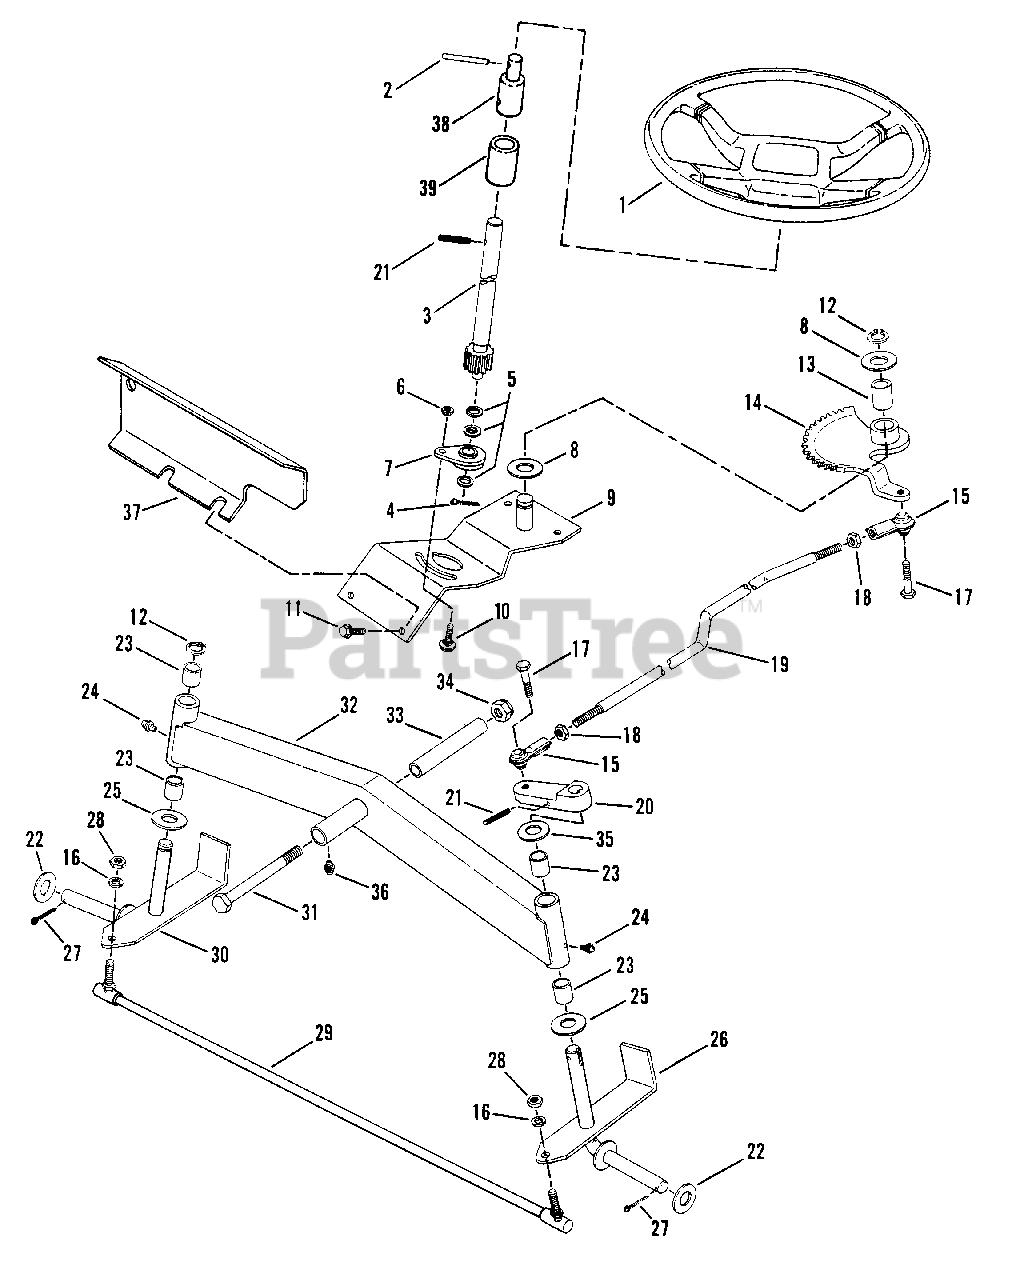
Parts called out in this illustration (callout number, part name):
1	WHEEL, Steering
2	PIN, 1/4 x 2-1/4" Roll
3	SHAFT, Steering
4	PIN, Cotter 3/32" x 1"
5	WASHER, Shim .5 x .75 x .03
6	NUT, 1/4-20 Hex Flange Lock
7	ADJUSTER, Steering
8	WASHER, Thrust
9	ASSEMBLY, Steering Support
10	BOLT, 1/4-20 x 5/8" Short Neck Carriage
11	SCREW, 5/16-18 x 5/8" Self-Tapping
12	RING, Retaining EXT .625
13	BEARING, DX, 3/4X1
14	ASSEMBLY, Sector
15	BALL JOINT, Drag Link .377 ID Ball x 3/8-24 End
16	WASHER, 3/8 Split Lock
17	SCREW, 3/8-24 x 1-1/4" Hex Head Cap
18	NUT, 3/8-24 Hex Jam
19	DRAG-LINK
20	ARM, Steering
21	PIN, 1/4 x 1 1/4" Roll
22	WASHER, 49/64 x 1-1/2" O.D. Flat
23	BEARING, Sleeve .875 OD
24	LUBE FITTING, Straight (press-fit for .187 dia. Hole)
25	WASHER, Thrust
26	ASSEMBLY, Spindle (Left Hand)
27	PIN, 5/32 x 1" Cotter
28	NUT, 3/8-24 Hex
29	TIE-ROD
30	ASSEMBLY, Spindle (Right Hand)
31	SCREW, 1/2-20 x 4 1/2" Hex Head Cap
32	ASSEMBLY, Front Axle
33	SPACER, Axle Pivot .748 OD x .508 ID x 3.77 L
34	NUT, 1/2-20 Hex Lock
35	WASHER .77 x 1.13 x .06
36	FITTING, Lube 3/16
37	HEAT SHIELD, Fuel Line
38	ADAPTER, Steering Wheel
39	COVER, Steering Shaft
